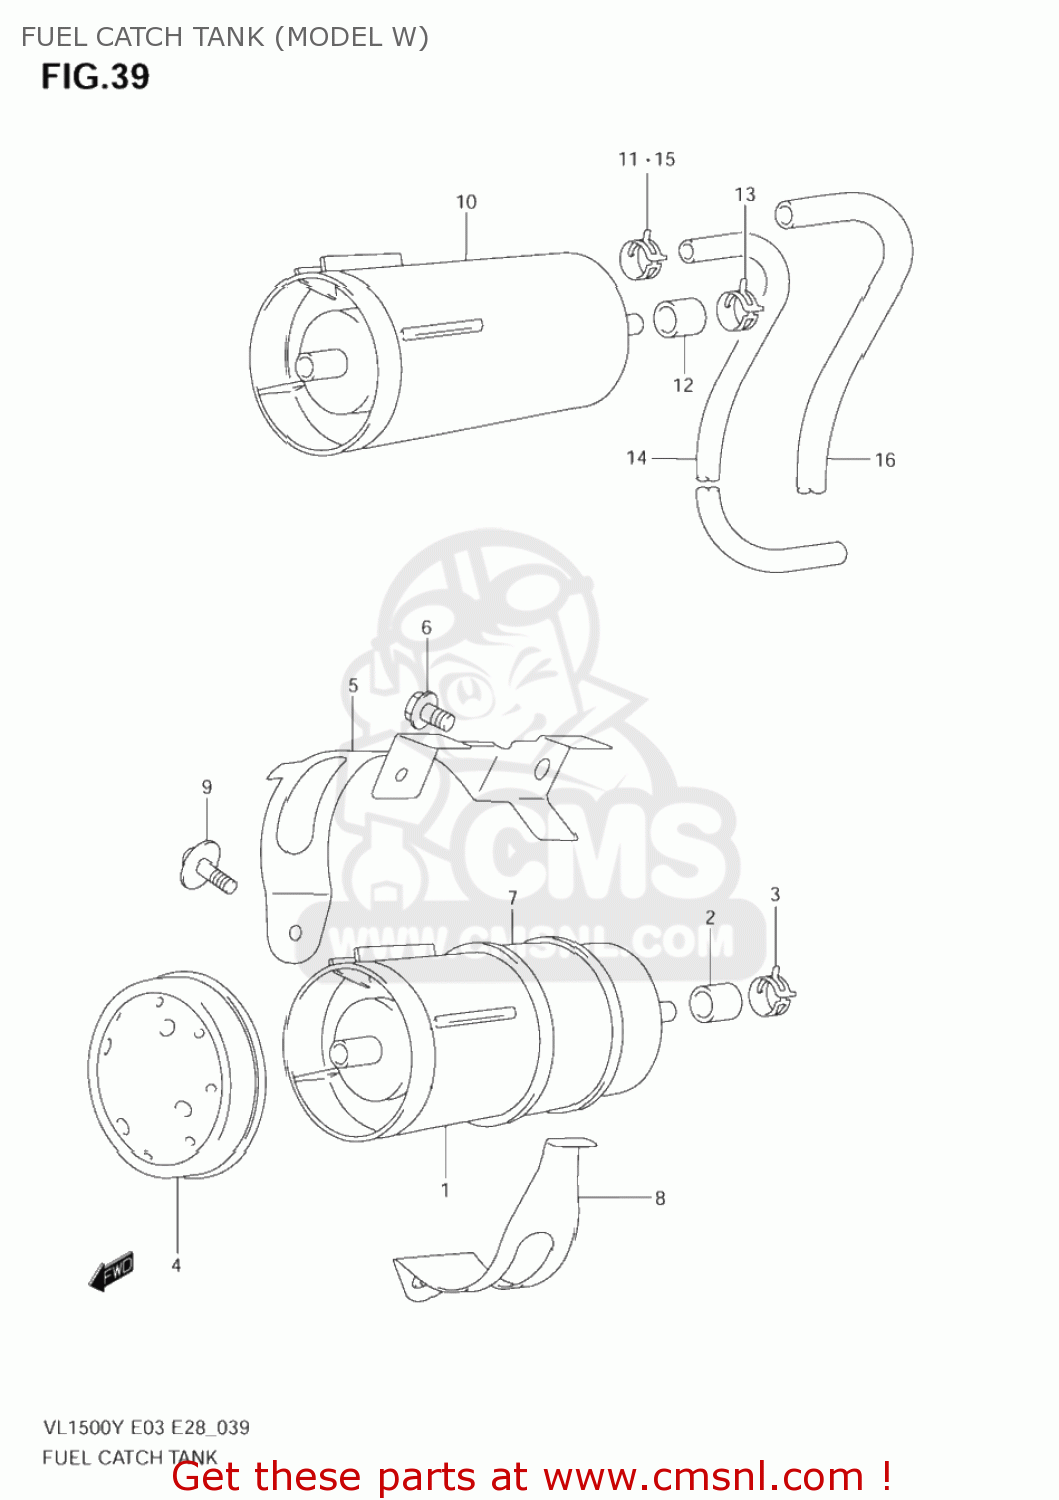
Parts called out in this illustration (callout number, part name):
1	TANK,FUEL CATCH
2	CAP,OD:11.5
3	CLIP
4	CAP,CANISTER
5	BRACKET,CATCH TANK
6	BOLT(6X16)
7	CUSHION,CANISTER
8	HOLDER,CATCH TANK
9	SCREW 6X12
10	CANISTER ASSY,CHARCOAL
11	CLIP
12	CAP,OD:11.5
13	CLIP
14	HOSE,CANISTER & CARB PURGE
15	CLIP
16	PROTECTOR(14.5X15.5X600)
